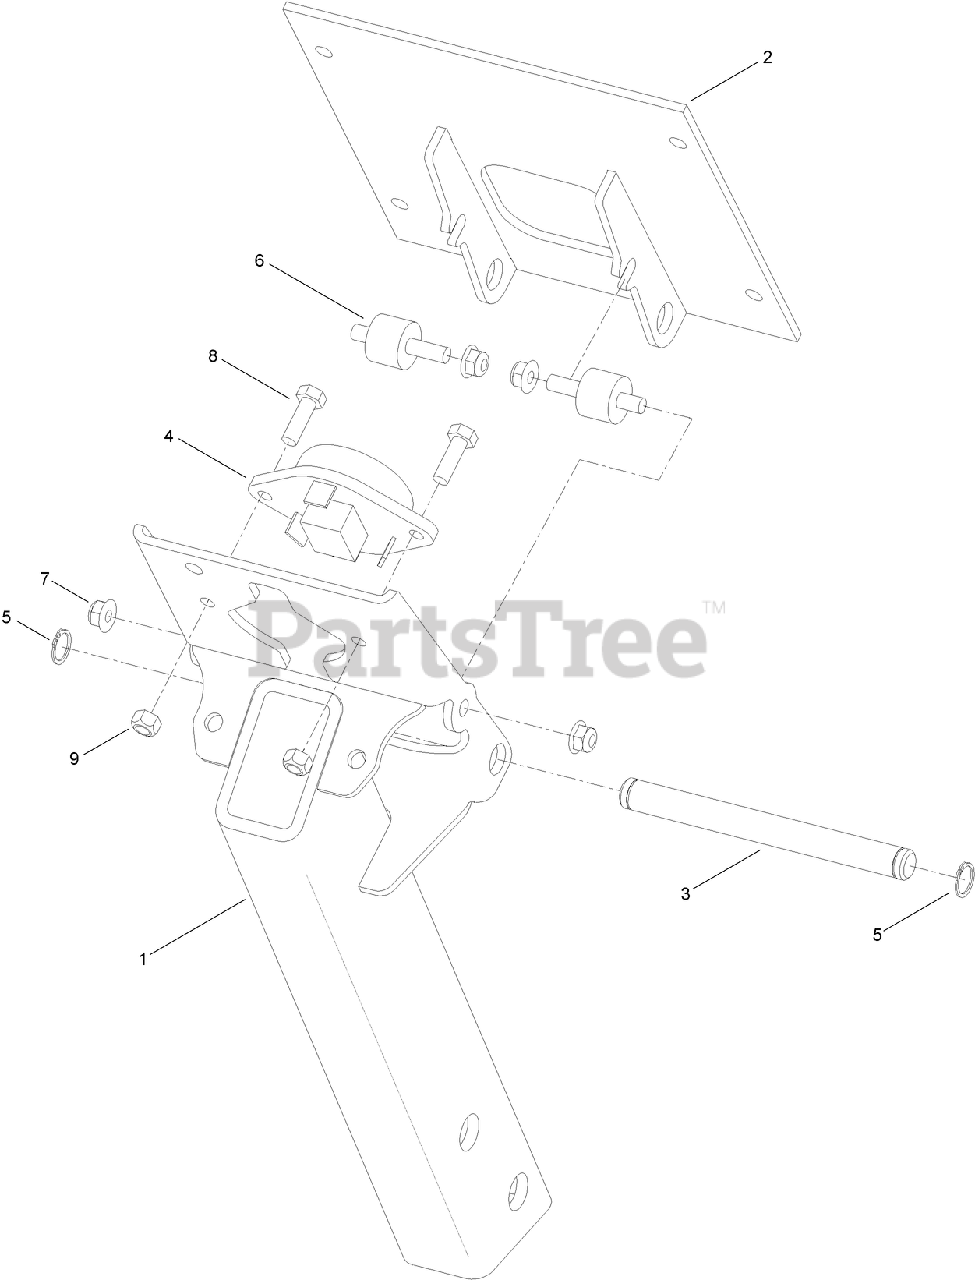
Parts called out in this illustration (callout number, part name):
1	POST-SEAT
2	PAN-SEAT
3	PIN-PIVOT
4	SWITCH-OPS
5	RING-SNAP, EXTERNAL
6	MOUNT-RADIATOR
7	NUT-HF, NI
8	SCREW-HHF
9	NUT-LOCK, NI
